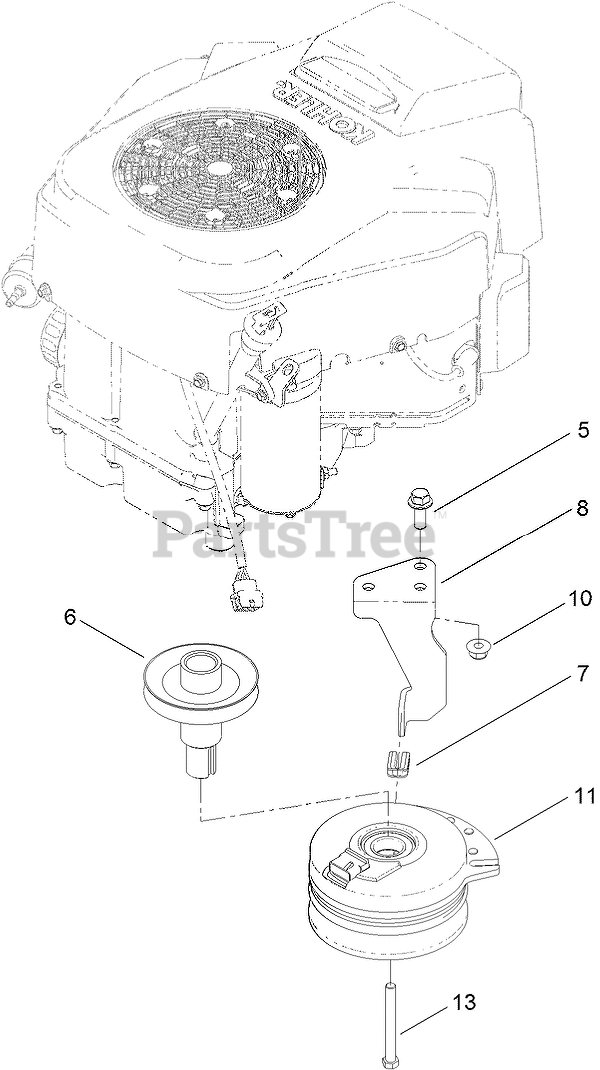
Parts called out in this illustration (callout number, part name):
5	SCREW-HHF
6	PULLEY-ENGINE
7	ISOLATOR-CLUTCH
8	STOP-CLUTCH
10	NUT-HF, NI
11	CLUTCH-ELECTRIC
13	SCREW-HH
